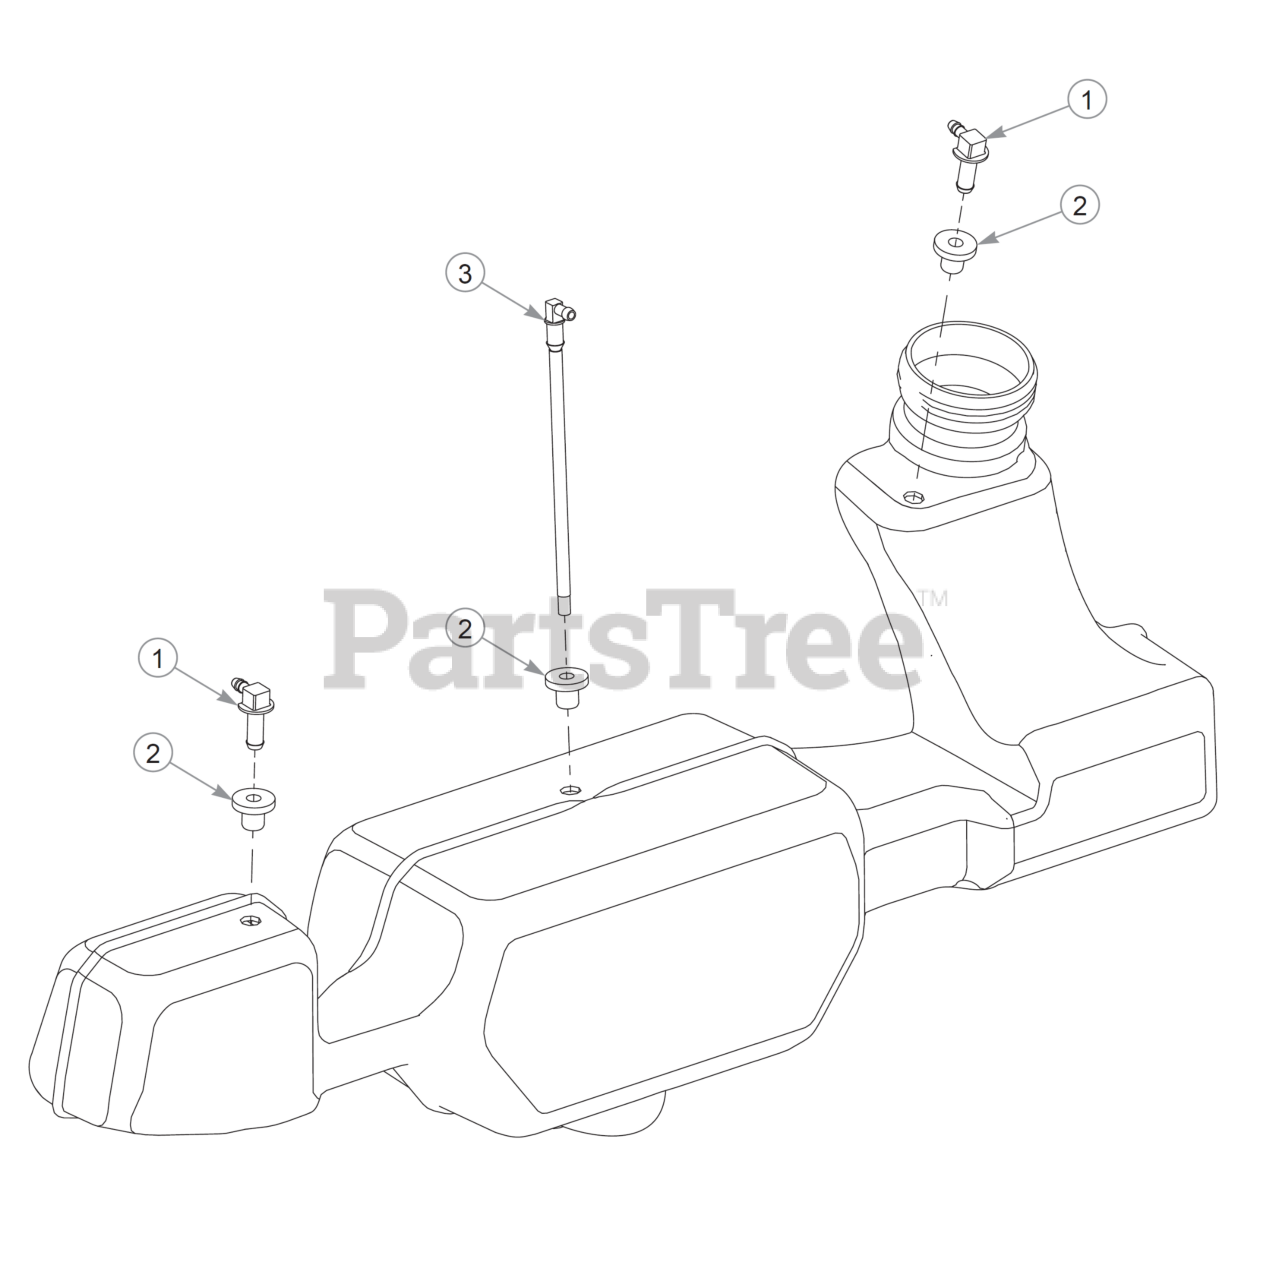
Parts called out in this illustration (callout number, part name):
1	VENT FITTING SVC KIT
2	GROMMET SVC KIT
3	SUCTION HOSE SVC KIT
